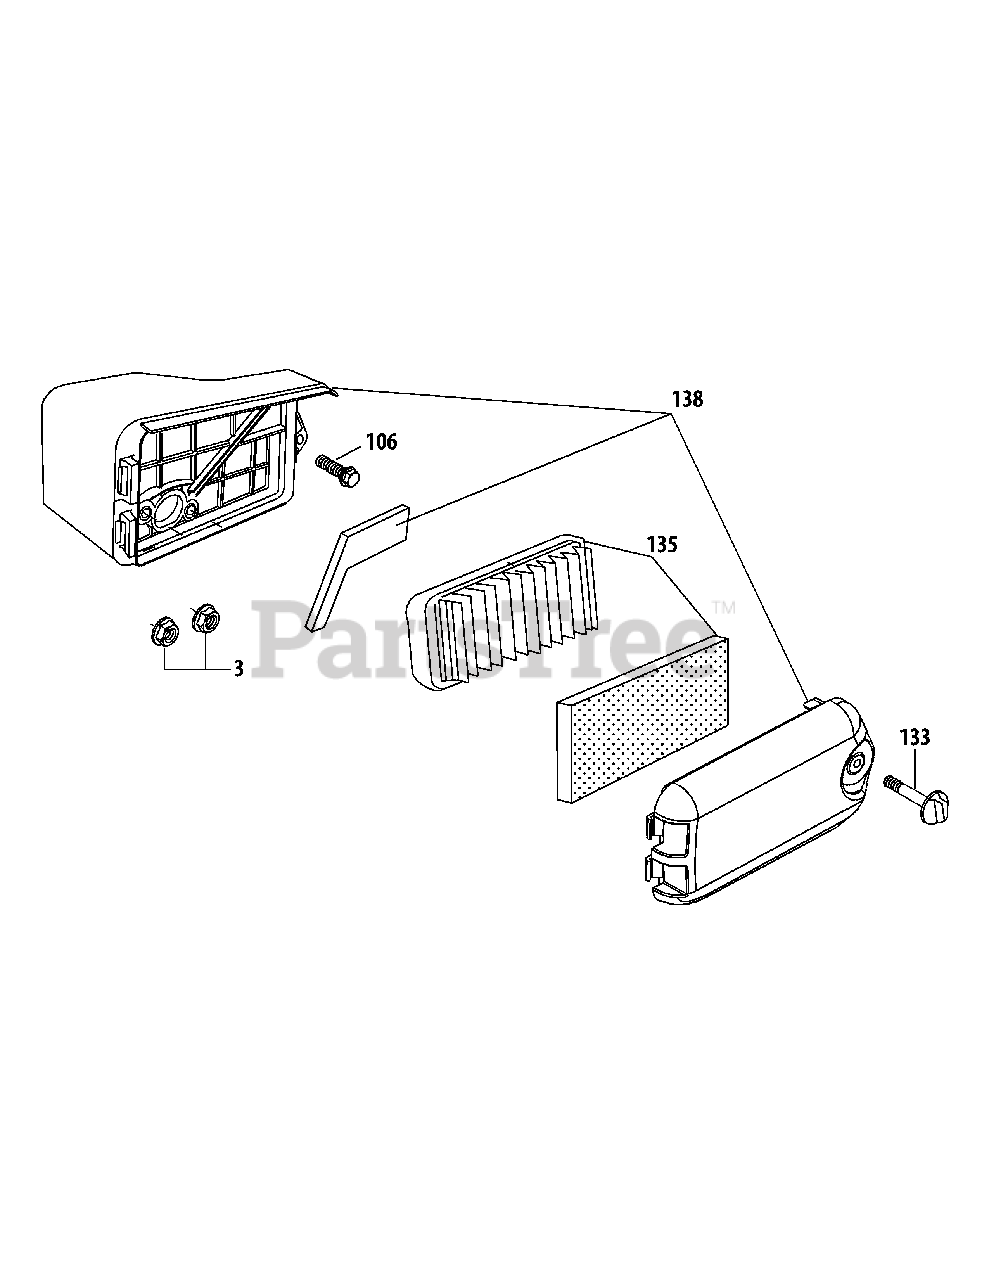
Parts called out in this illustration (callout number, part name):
3	Nut M6X10Mm
106	Bolt M6X35
133	Air Filter Cover Thumb Screw
135	Air Cleaner Filter Kit
138	Air Cleaner Housing Assy
